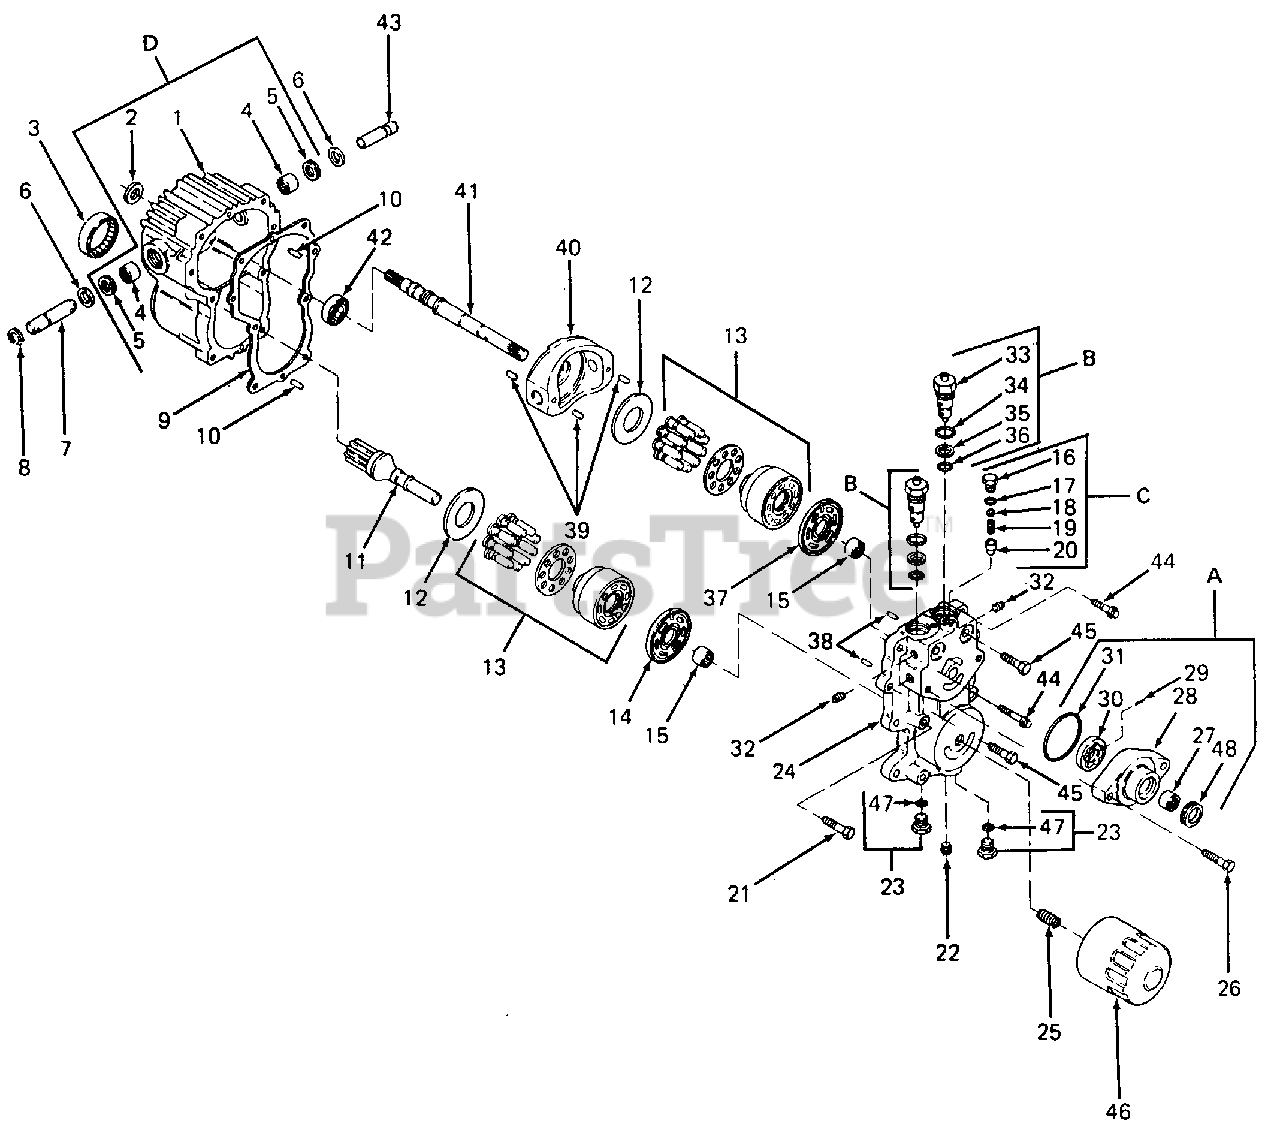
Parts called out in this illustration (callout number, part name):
1	Housing, Transmission
2	Seal, Lip
3	Bearing, Roller
4	Bearing, Needle
5	Seal, Lip
7	Shaft, Trunnion
8	Ring, Retaining
9	Gasket
10	Pin
11	Shaft, Motor
12	Plate, Thrust
13	Block, Cylinder
14	Plate, Valve
15	Bearing, Roller
16	Plug
17	O-Ring
18	Kit, Shim Pack
19	Spring, Relief Valve
20	Cone, Relief Valve
24	Center Section
27	Bearing, Needle
28	Charge Pump Housing
30	Gerotor
33	Valve
35	Ring, Back-up
37	Plate, Valve
41	Shaft, Pump
43	Shaft Assembly, Trunnion
44	Screw, 12 Point
46	Oil Filter
48	Seal, Lip
A	Kit, Charge Pump
B	Valve Assembly
C	Kit, Relief Valve
D	Housing Assembly
